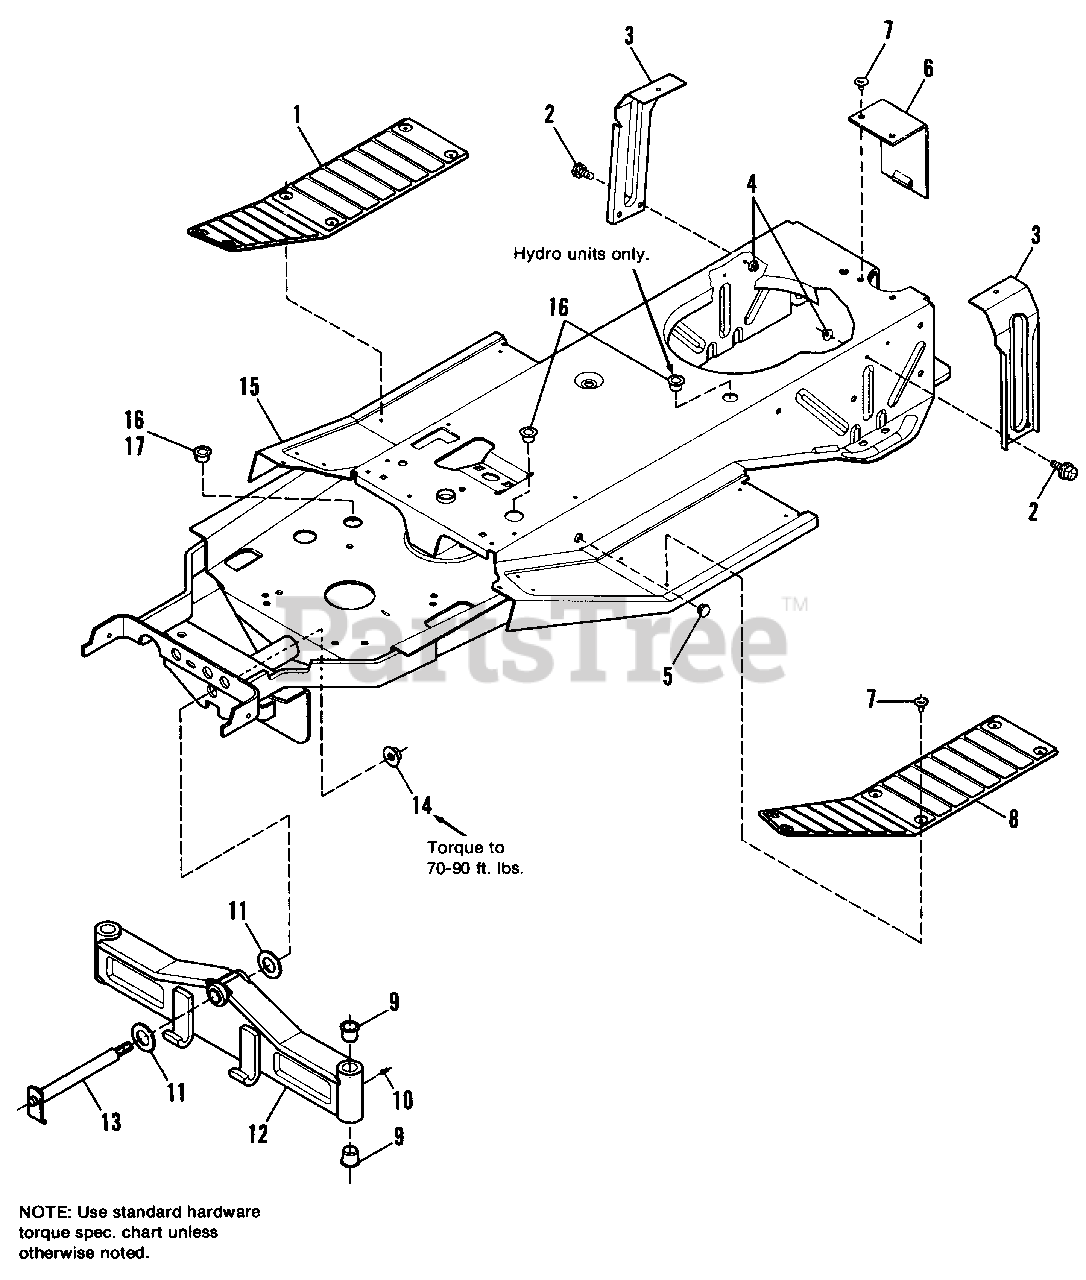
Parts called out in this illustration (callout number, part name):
1	PAD, Footrest, R.H.
2	CAPSCREW, Hex, Flange Whizlock, 3/8-16 x 1
3	SUPPORT, Seat
4	NUT, Hex, Esna Lock, 3/8-16
6	COVER, Rear
7	FASTENER, Panel
8	PAD, Footrest, L.H.
10	GREASE, Fitting
11	WASHER, Special
12	AXLE ASSY., Front
13	AXLE PIVOT ASSY.
14	NUT, Hex Full Lock, 3/4-16
15	FRAME ASSY.
16	BUSHING, Snap (Qty. 3-16 HP Hydro; Qty. 2-12.5 HP Hydro; Qty. 1-12.5 HP Gear)
17	BUSHING, Snap (Used on 12.5 HP Gear Only)
